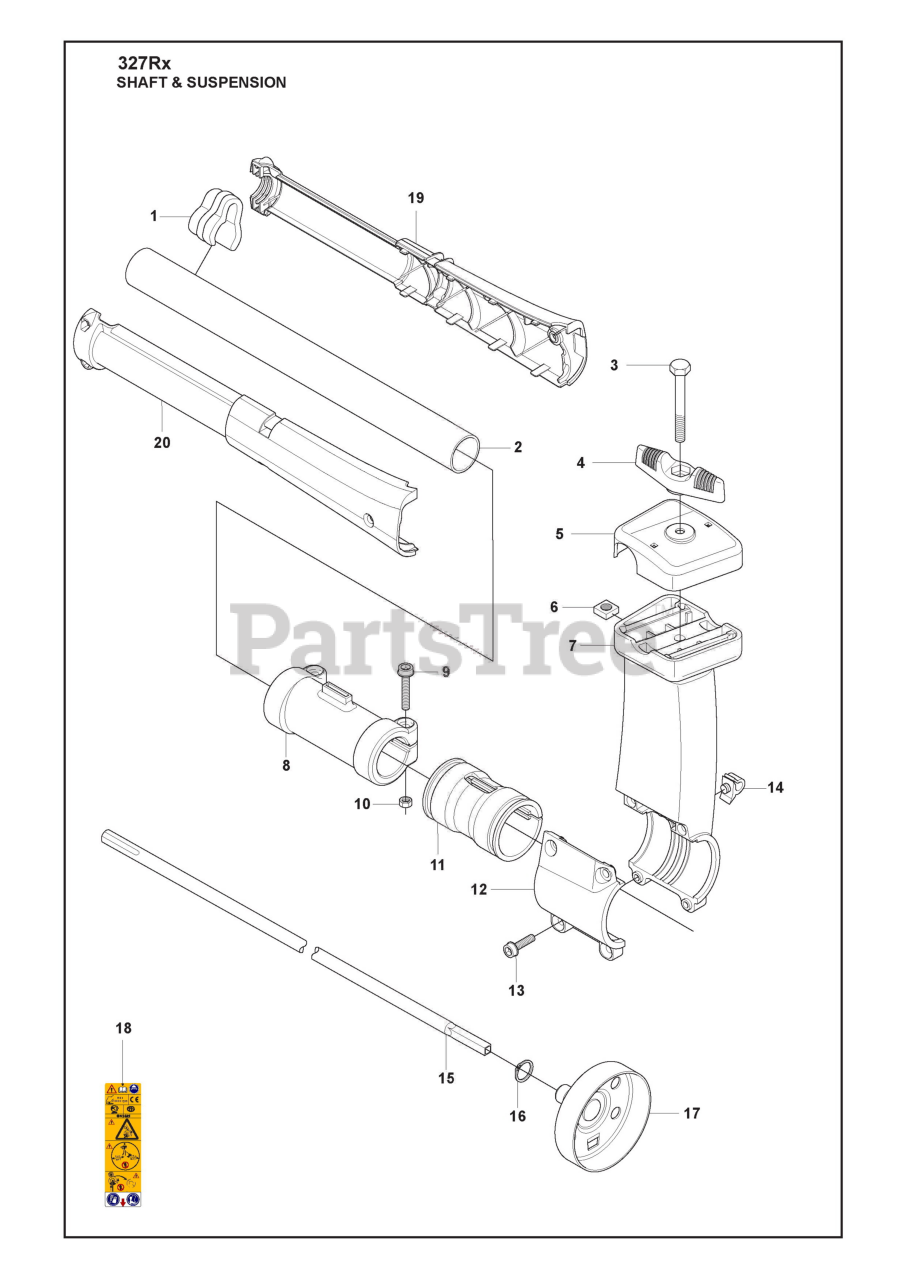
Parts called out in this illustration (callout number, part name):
2	DRIVE TUBE ASSEMBLY
3	%SCREW
5	PROTECTOR CLAMP
7	%BRACKET
8	COMPRESSION SLEEVE Ã 24
11	VIBRATIONS ABSORBER
12	COVER, BRACKET
13	SCREW
15	DRIVE SHAFT
16	RETAINING RING SGA 10
17	CLUTCH DRUM
18	RP WARNING DECAL
